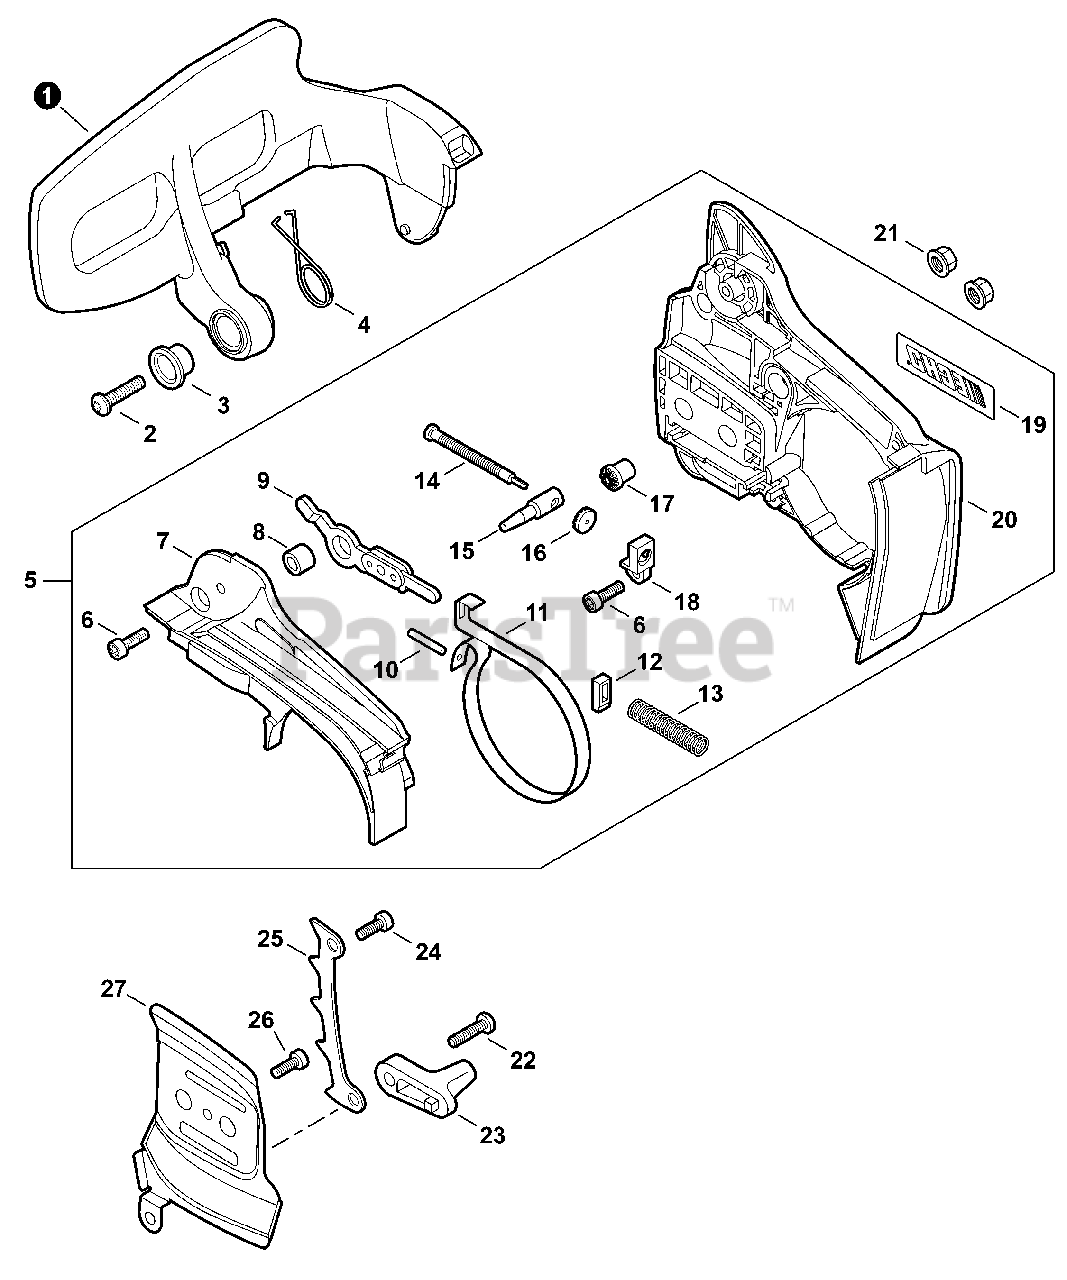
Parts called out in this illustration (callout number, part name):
1	LEVER, BRAKE
2	BOLT, TORX 5×12
3	COLLAR 10
4	SPRING, TORSION
5	BRAKE ASSY, CHAIN
6	BOLT, TORX 4×12
7	COVER, BRAKE
8	SPACER 8×12×9
9	CONNECTOR, BRAKE
10	PIN, SPRING 3×9.8
11	BAND, BRAKE
13	SPRING, COMPRESSION
15	TENSIONER, CHAIN
16	GEAR, BEVEL
17	GEAR, BEVEL
18	COLLAR 8
19	LABEL, ECHO
20	GUARD, SPROCKET
22	BOLT, TORX 5×20
23	CHAIN CATCHER
24	BOLT, TORX 5×16
25	SPIKE, BUMPER
26	BOLT, TORX 4×12
27	PLATE, GUIDE - INNER
